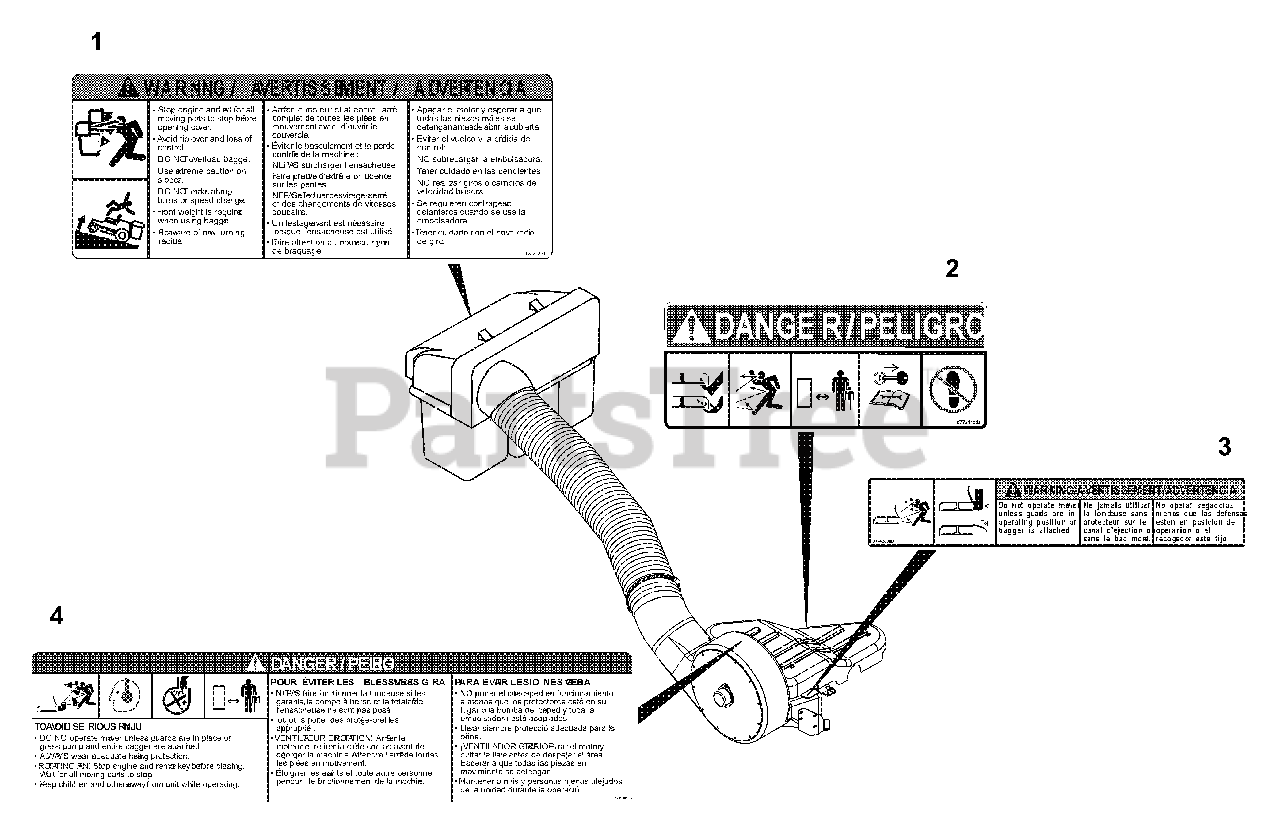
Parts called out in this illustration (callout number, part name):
1	DECAL-BAGGER HOOD EZR
2	DECAL, MOWER PAN DANGER
3	DECAL, WARNING
4	DECAL-CAUTION, GRASS PUMP
